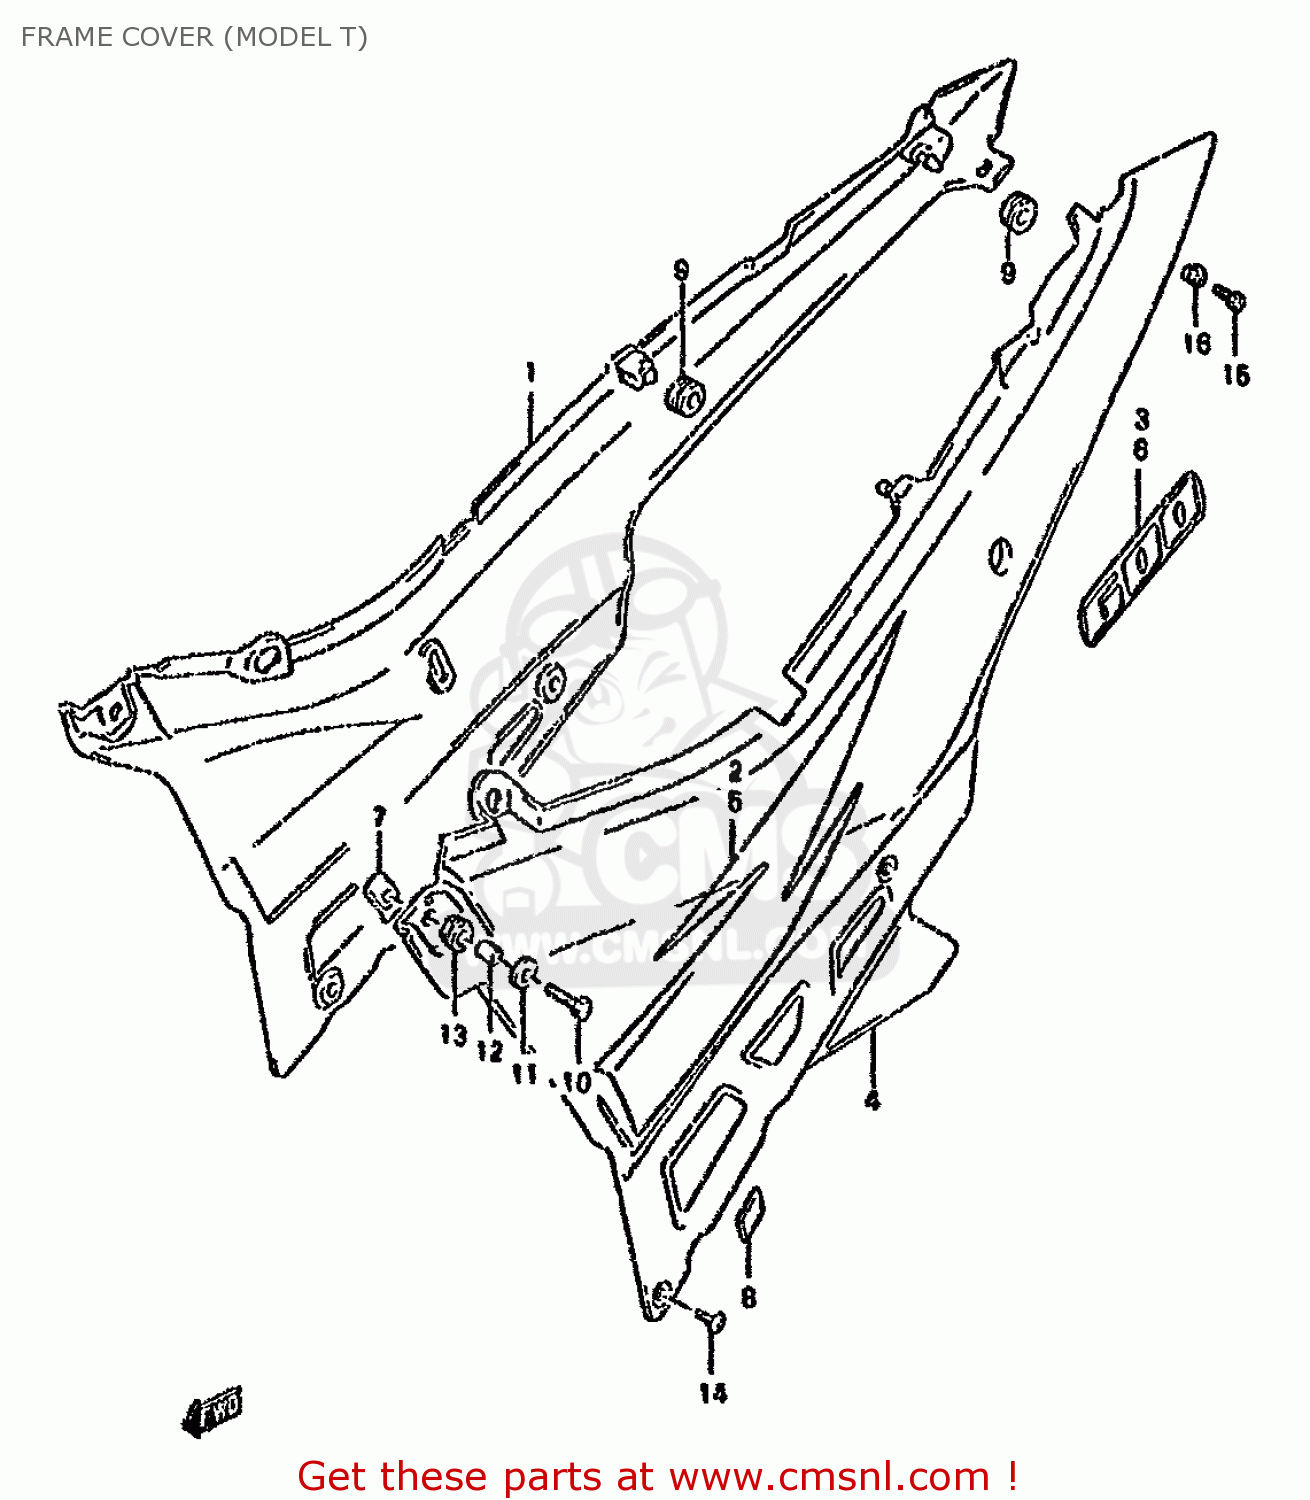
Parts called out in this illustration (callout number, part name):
1	COVER,FRAME,R
2	TAPE,FRAME COVER,R
3	EMBLEM,FUEL COVER
4	COVER,FRAME,L
5	TAPE,FRAME COVER,LEFT
6	EMBLEM,FUEL COVER
7	PLATE,FRAME COVER
8	CUSHION,FRAME COVER
9	CUSHION
10	SCREW(6X20)
11	WASHER
12	SPACER (6.1X9X9)
13	CUSHION
14	SCREW 5X12
15	WASHER
16	WASHER
17	WASHER
18	SPACER (6.1X9X9)
19	WASHER
20	SCREW(5X15.3)
21	CUSHION
22	SCREW(5X15.3)
